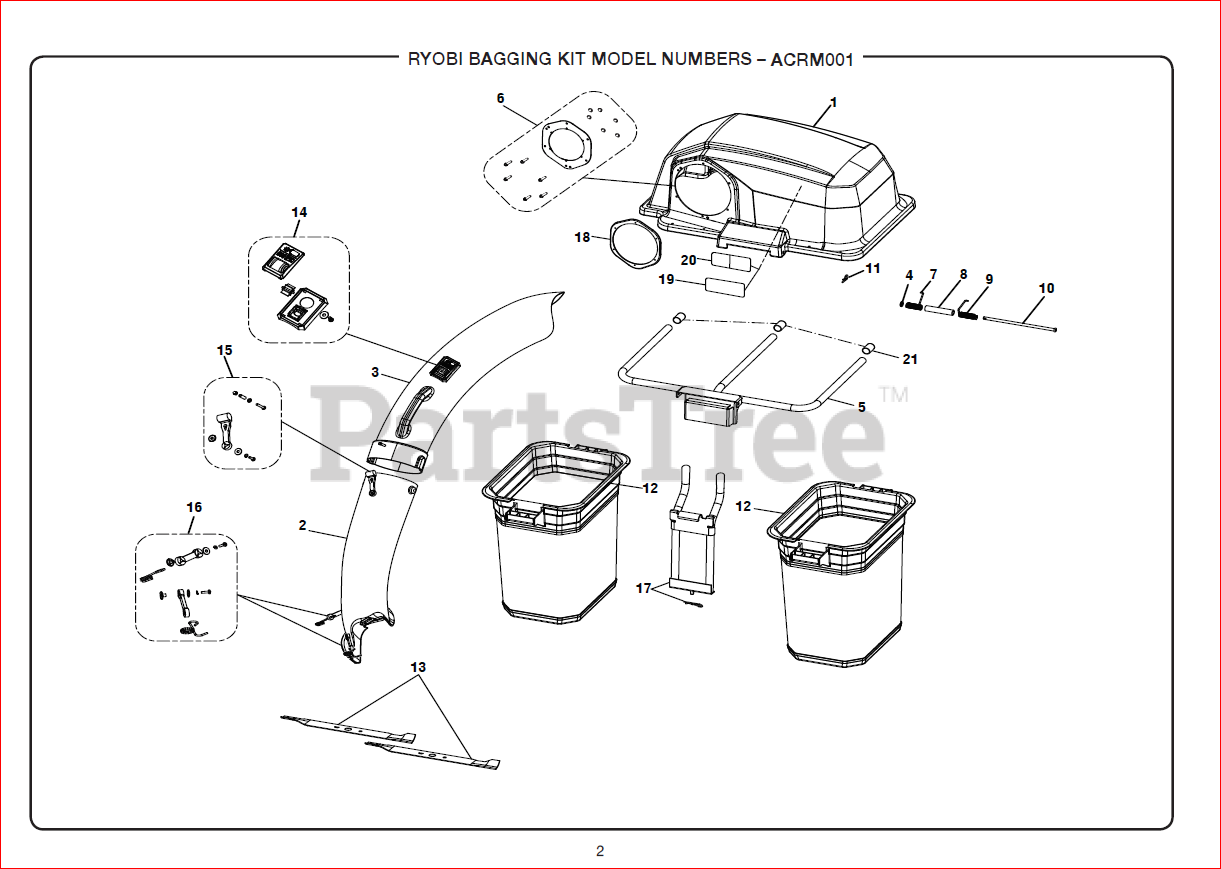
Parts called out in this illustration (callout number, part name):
1	Bagger Cover Assembly
2	Lower Bagger Tube Assembly
3	Upper Bagger Tube Assembly
5	Upper Frame Cover Assembly
7	Bagger Hinge Spring (Right)
8	Cover Hinge Bushing
9	Bagger Hinge Spring (Left)
10	Hinge Bagger Cover Pin
11	Bagger Hinge Pin Lock
12	Bagger Assembly Bag
13	Blade (43 cm)
14	Bagger Gauge Assembly
15	Upper Bungie Tube Connector Kit
16	Lower Bungie Tube Connector Kit
17	Bagger Assembly Lower Frame
18	Bagger Cover Bracket
19	Bagger Warning Label
20	Bagger Icon Warning Label
21	Hanger Cap
